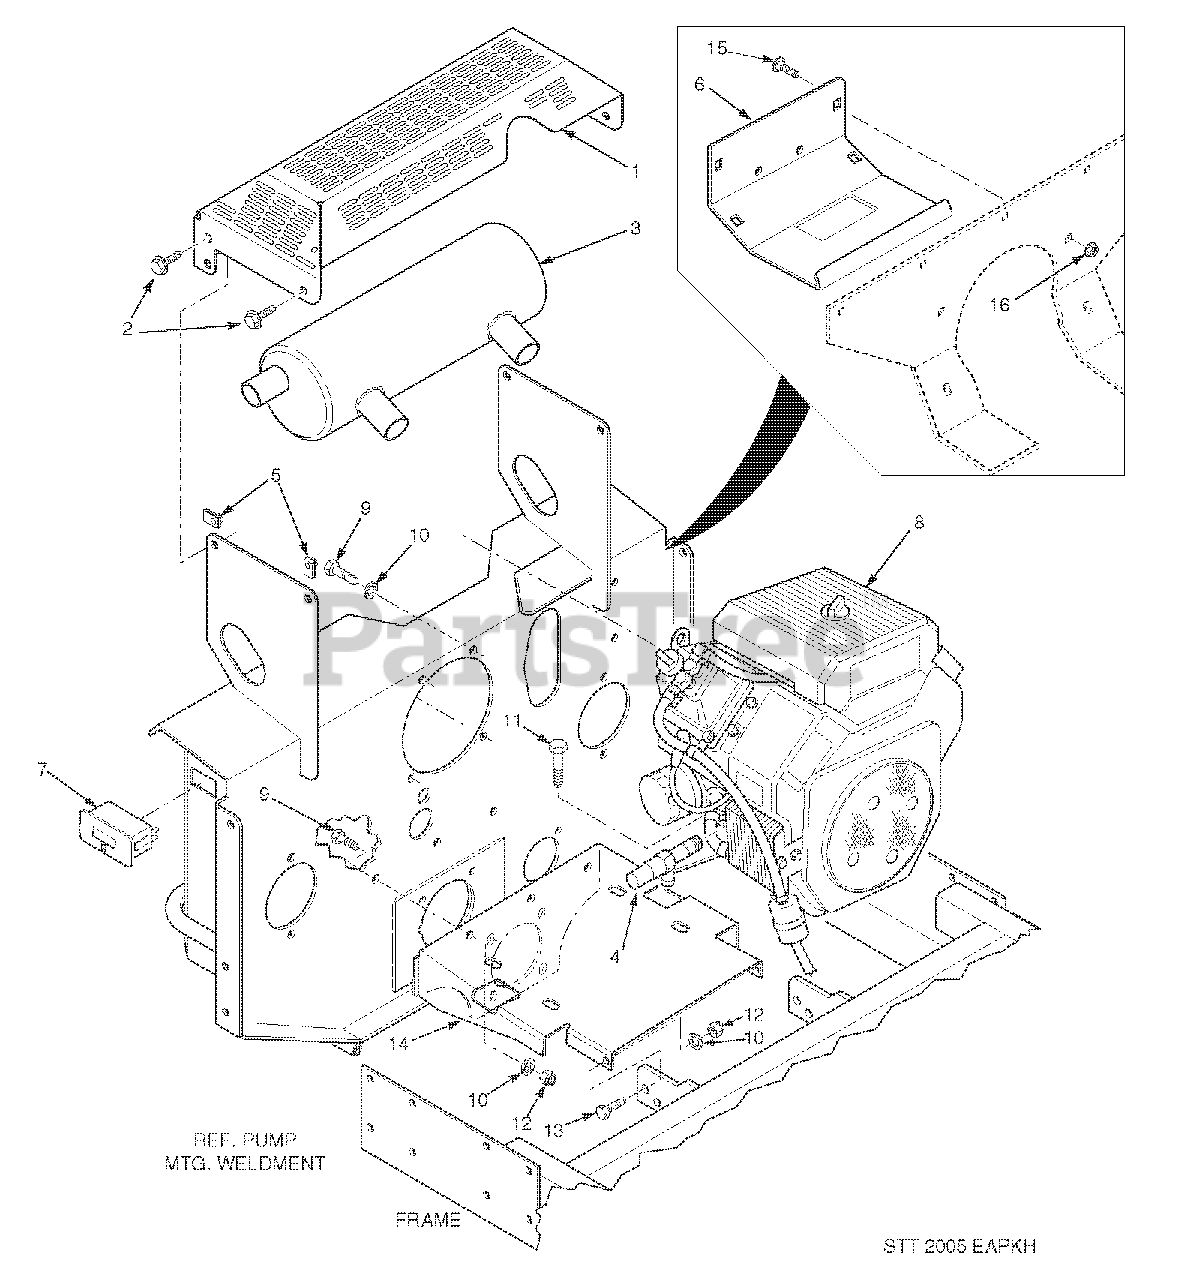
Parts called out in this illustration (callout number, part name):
1	Muffler Guard
2	Screw, Hex Serrated Flange 1/4-20 x 3/4"
3	Muffler, Part Of Engine
4	Oil Drain Extension
5	U-Nut, 1/4-20
6	Rear Cover
7	Hour Meter
8	Engine, Kohler 25 CH LP
9	Bolt, Hex Head 3/8-16 x 1"
10	Lockwasher, 3/8" Spring
11	Bolt, Hex Head 3/8-16 x 1-3/4"
12	Nut, Hex Elastic Stop 3/8-16
13	Bolt, Hex Head 3/8-16 x 1-1/4"
14	Plate, Engine Mounting
15	Bolt, Carriage 5/16-18 x 3/4"
16	Nut, Hex Serrated Flange 5/16-18
